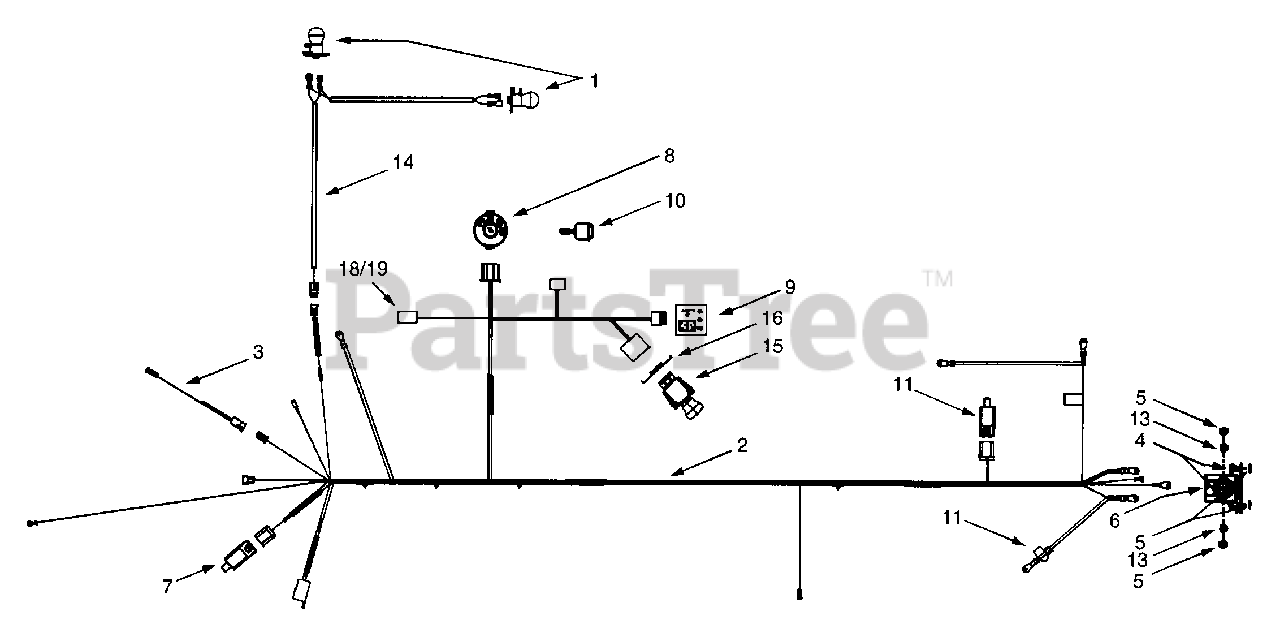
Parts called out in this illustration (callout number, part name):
1	Bulb/Socket Headlight Assembly
2	Wiring Harness
3	Harness Adapter, #18 x 5
4	Self Tapping Screw, 1/4-20 x.5
5	Hex Nut, 1/4-20
6	Solenoid, 12-volt, 100 Amp
7	Snap Mount Safety Interlock Switch (Brake)
8	Ignition Switch
9	Systems Indicator w/Ammeter
10	Ignition Key
11	Safety Plunger Switch (Seat)
13	Lock Washer, 1/4
14	Headlight Harness
15	Electric PTO Switch
16	Retainer Bracket
18	Fuse Holder
19	20-amp Fuse
